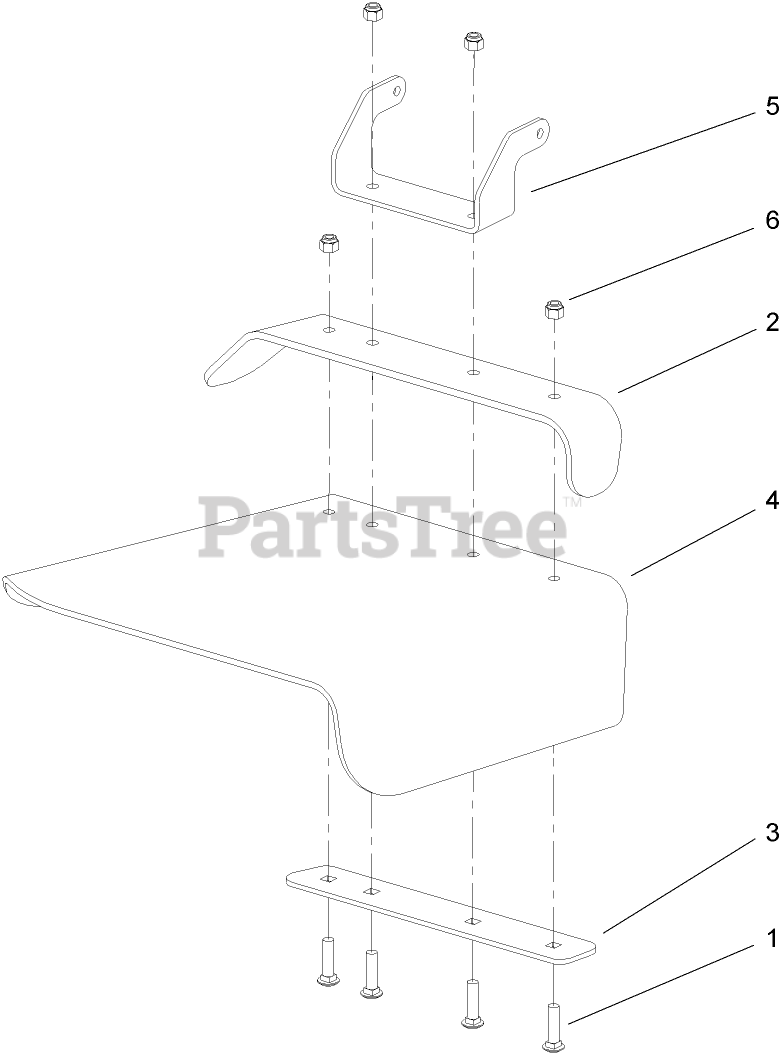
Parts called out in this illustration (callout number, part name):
1	SCREW-CARR
2	DEFLECTOR
3	STRAP-DISCHARGE
4	DEFLECTOR-RUBBER
5	BRACKET-MOUNTING, DEFLECTOR
6	NUT-LOCK, NI
